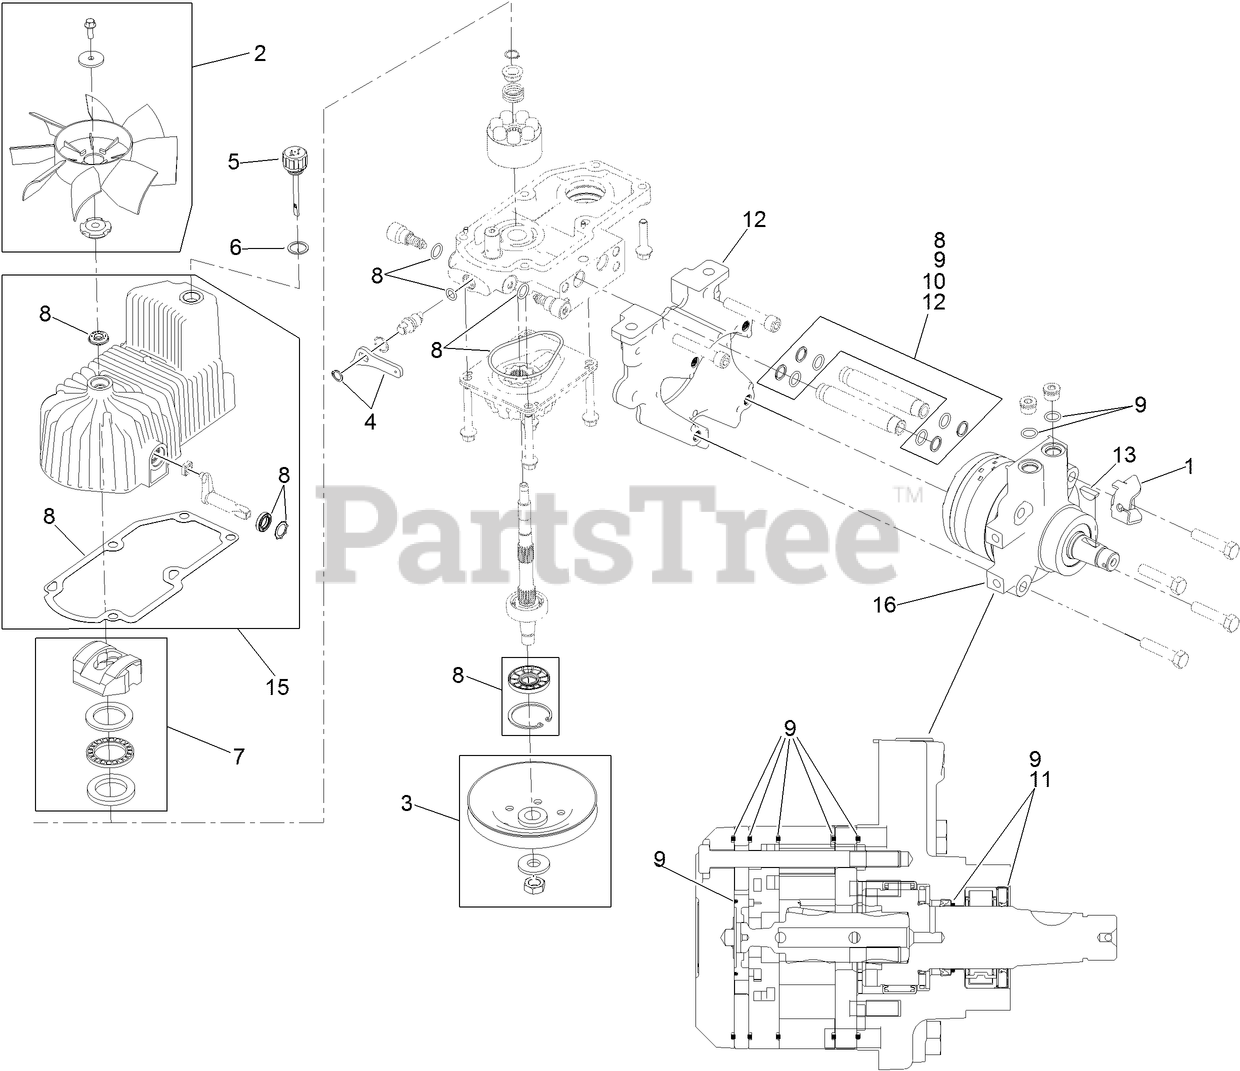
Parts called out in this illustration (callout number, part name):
1	BRACKET-ANCHOR, CABLE
2	FAN KIT
3	PULLEY KIT
4	HANDLE-BYPASS VALVE, HYDRO
5	DIPSTICK-HYDRO W/GASKET
6	GASKET-DIPSTICK, HYDRO
7	SWASH BLOCK KIT
8	PUMP SEAL KIT
9	MOTOR SEAL KIT
10	TUBE SEAL KIT
11	OUTPUT SHAFT SEAL KIT
12	CUP-NOSE
13	KEY-WOODRUFF
15	HOUSING-HYDRO, RH
16	MOTOR-HYDRAULIC, RH 280CC
